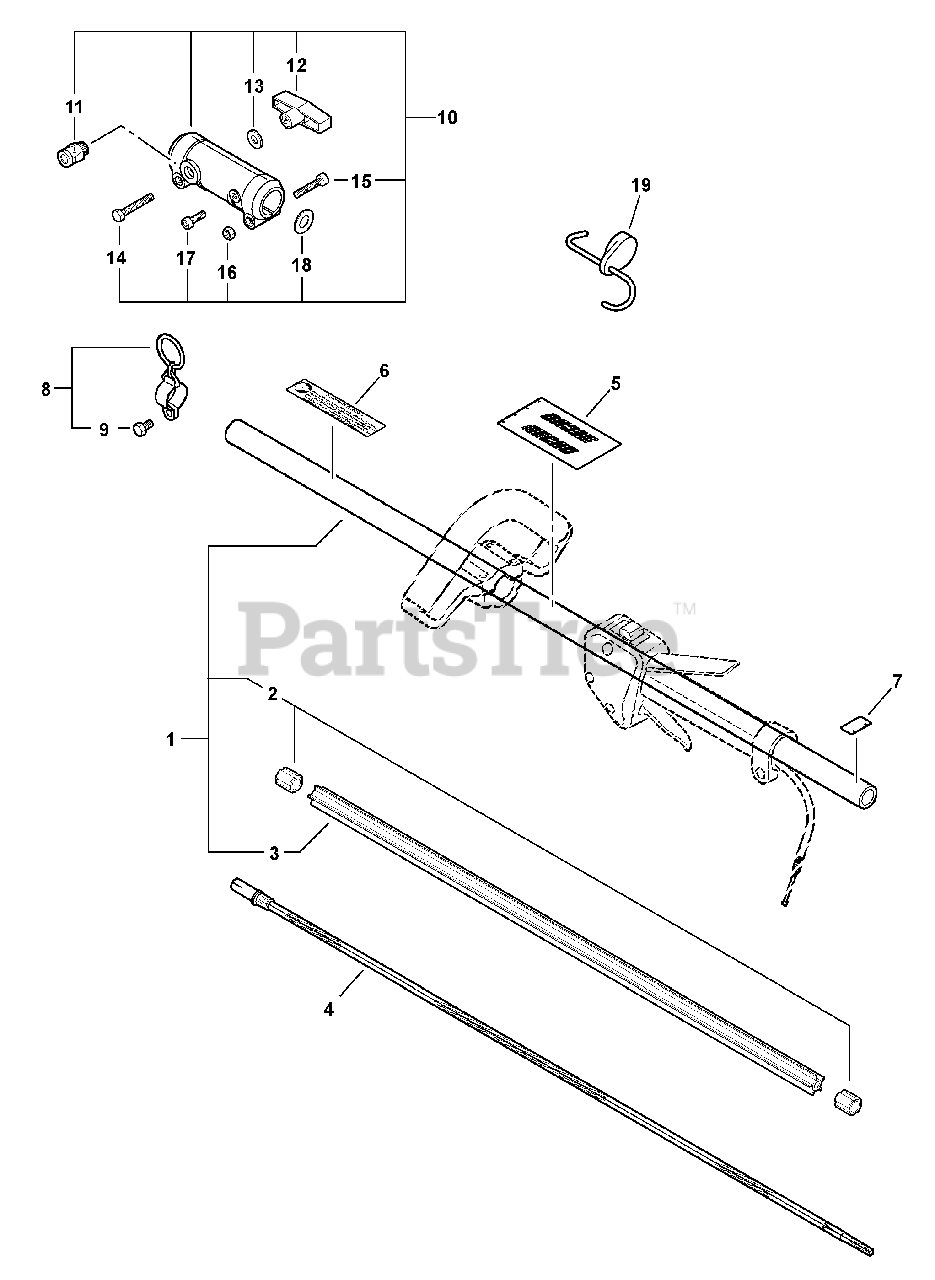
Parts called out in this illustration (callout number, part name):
1	MAIN PIPE ASSY
3	LINER - FLEXIBLE
4	DRIVESHAFT - FLEXIBLE
5	LABEL, HANDLE LOCATION
6	LABEL, CAUTION
7	LABEL - ALIGNMENT
8	HANGER ASSY, HARNESS
9	BOLT 5×12
10	COUPLER ASSY
11	LATCH ASSY
12	KNOB, FASTENER
13	WASHER 6.6×20×1.6
14	BOLT 6×40
15	BOLT 6×25
17	BOLT M6×10
18	WASHER 18 SPR STEEL
19	HANGER, ATTACHMENT
